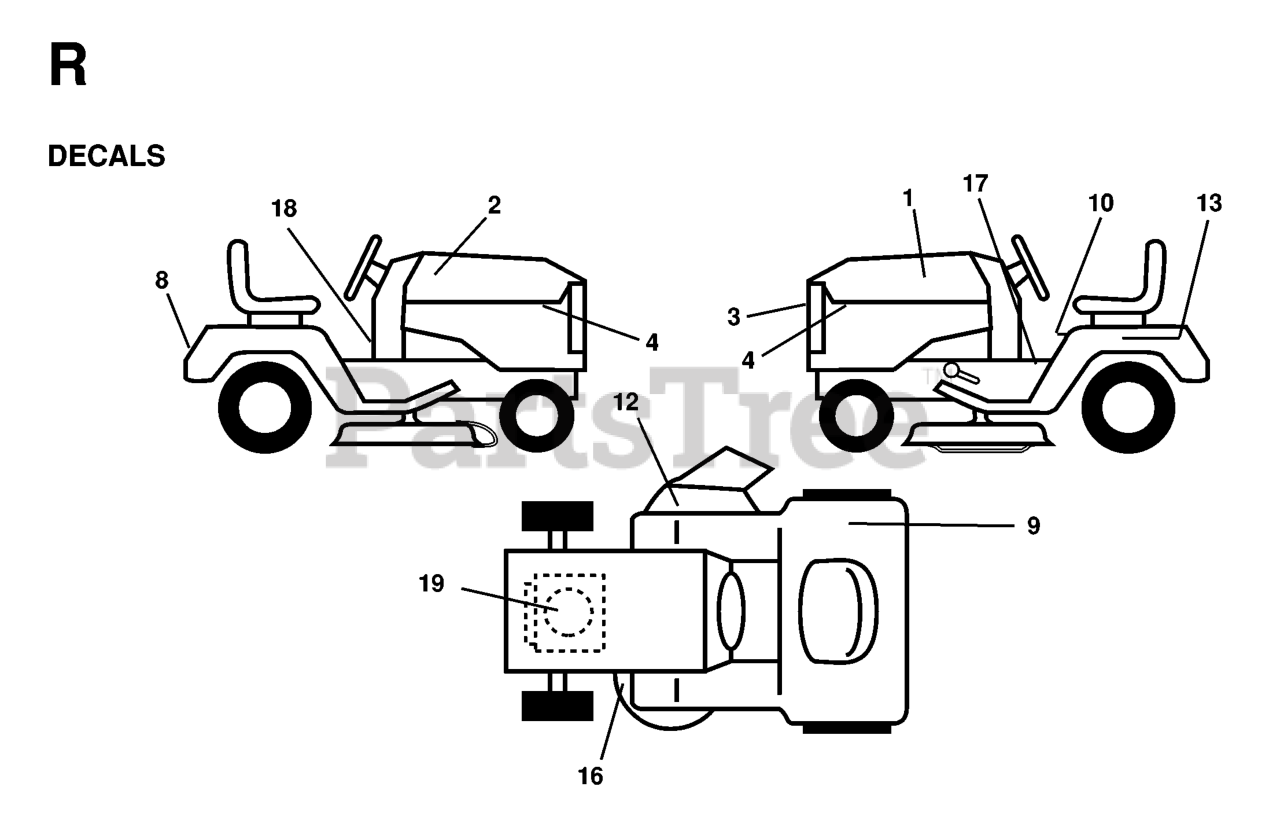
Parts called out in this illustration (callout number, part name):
3	DECAL.GRILLE.HUSQ
4	DECAL PNL SIDE
8	DECAL FENDER HUSQ
9	DECAL CERTIFICATION
10	DECAL READ OWNER'S MAN SYMS
12	DECAL MOWER CUT/FINGER
13	DECAL BTRY SYMBOLS
16	DECAL
17	Decal, Brake/Clutch Symbols
18	DECAL EUROPE STANDARD CE
